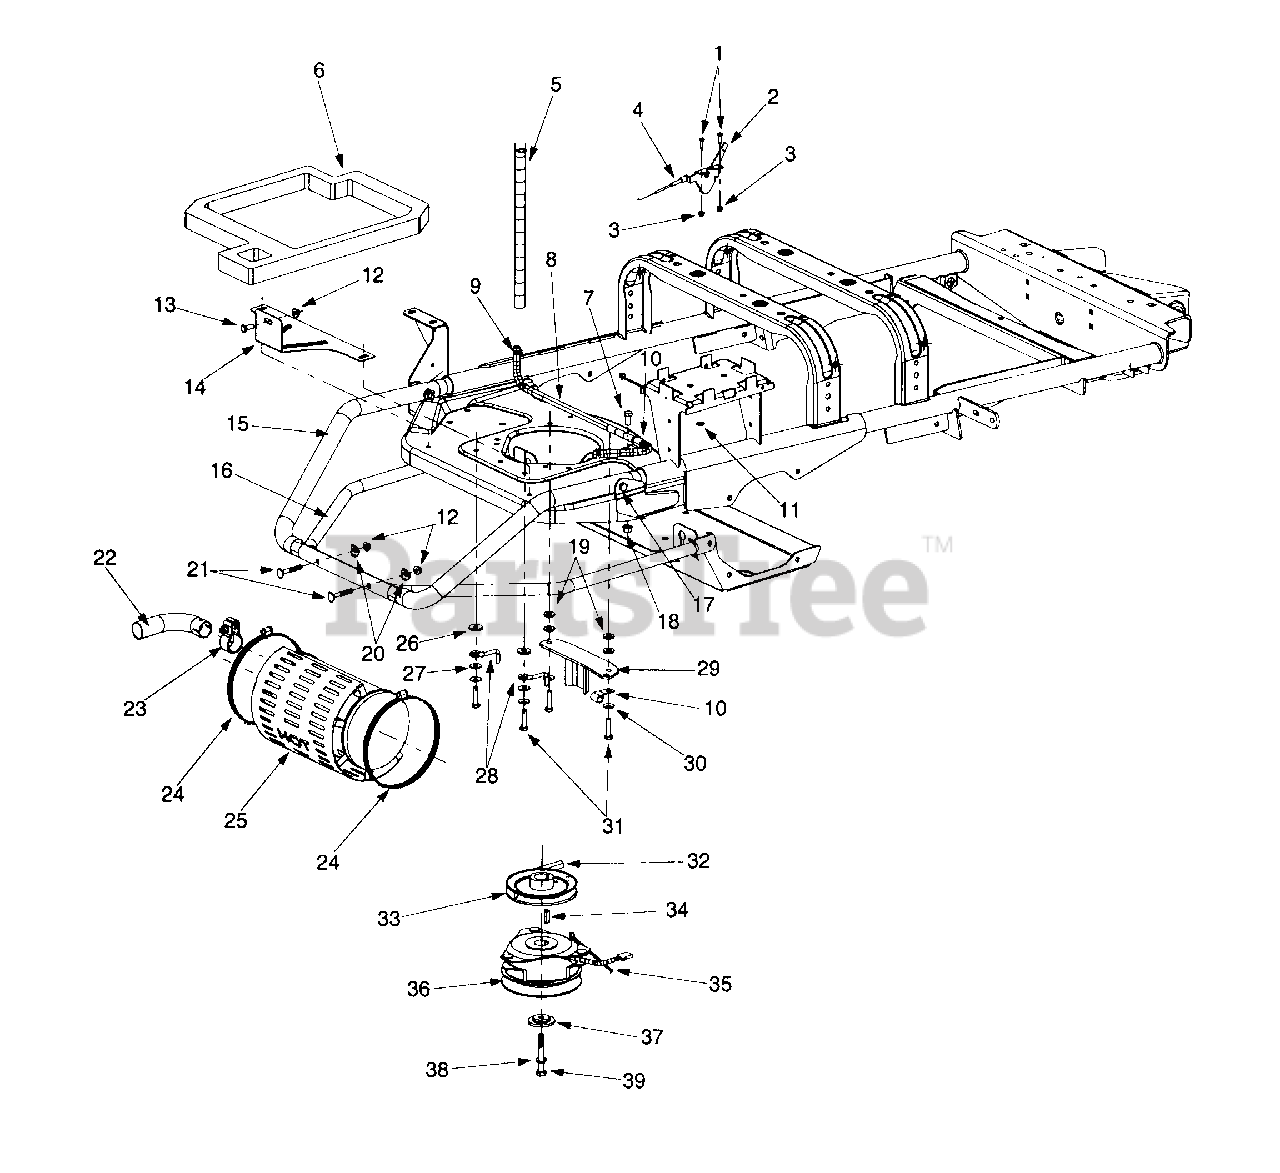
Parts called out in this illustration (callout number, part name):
1	Screw #10-24 x .750
2	Choke Control Cable 43.0"
3	Nylon Lock Nut #10-24
4	Throttle Control Cable 53.0"
5	Oil Drain Hose
6	Foam
7	Hex Cap Screw 3/8-16 x .75
8	Fuel Line Hose
9	Hose Clamp
10	Heat Shield Cable Clip
11	Lock Washer 5/16
12	Flange Lock Nut 5/16-18
13	Hex Cap Screw 5/16-18 x .75
14	Mounting Muffler Bracket
18	Flange Lock Nut 3/8-16
19	Flat Washer .407 ID x .812 OD
20	Shoulder Washer .320 ID x .93 OD
21	Carriage Bolt 5/16-18 x 2.0
22	Muffler Tube
23	Muffler Tube Clamp
24	Adjustable Clamp
27	Washer 5/16
28	Rear Belt Retainer Rod
31	Hex Cap Screw
32	V-Belt
34	Key 1/4 x 1.0
35	Cable Tie
36	Electric PTO Clutch
37	Spacer Clutch
38	Lock Washer 7/16
39	Hex Cap Screw
